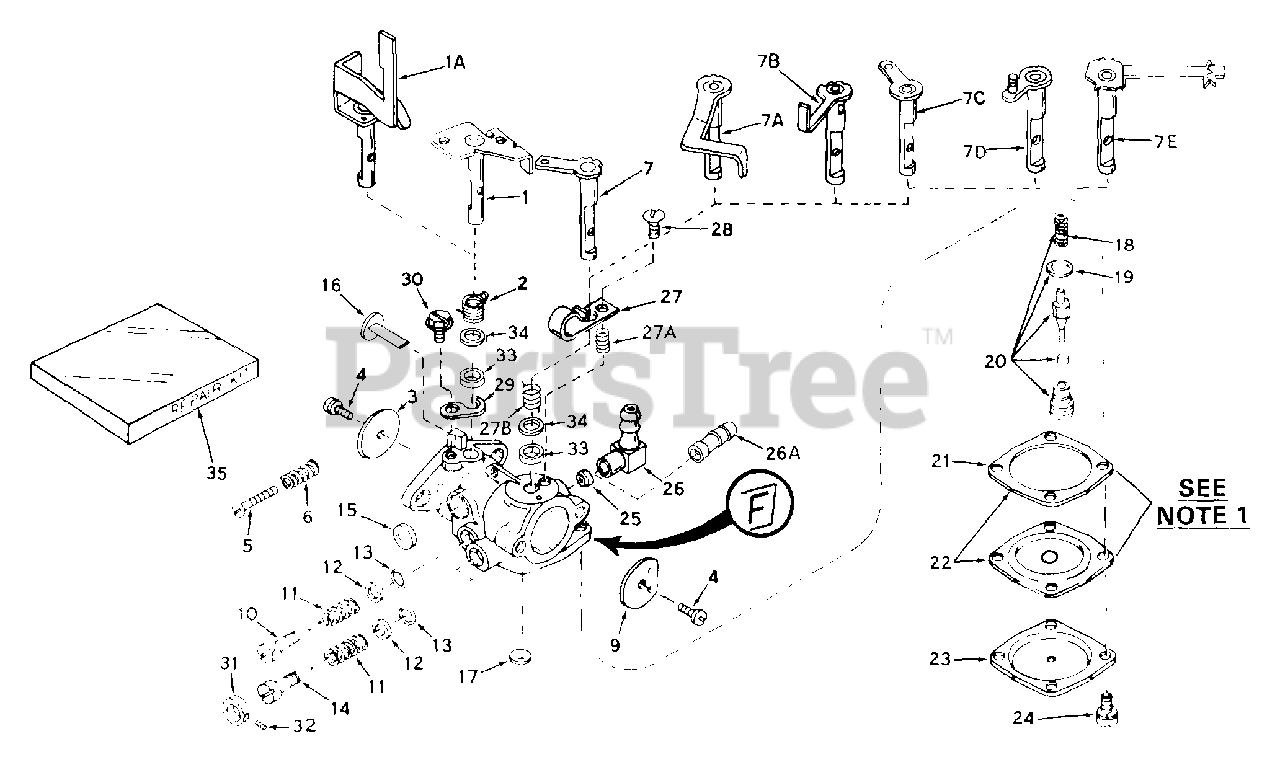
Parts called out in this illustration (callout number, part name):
1	"Shaft & Lever Assy., Throttle
2	Spring, Throttle return
3	Shutter, Throttle
4	Screw, Throttle & Choke shutter
5	Screw, Idle Regulating
6	Spring, Idle speed screw
7B	Shaft & Lever Assy., Choke
9	Shutter, Choke
10	Screw, Idle adj.
11	Spring, Adj. screw
12	Washer, Adj. screw
13	"O" Ring, Adj. screw
14	Screw, Main adj.
15	Plug, Welch
16	Element, Pump
17	Plug, Welch
18	Spring, Valve
19	Gasket, Valve seat
20	Inlet Needle, Seat, Spring & Gasket A ssy.,
21	Gasket, Diaphragm
22	Diaphragm Assy.
23	Cover, Diaphragm
25	Valve, Check
26	Fitting, Fuel inlet
27	Spring, Detent
29	Retainer, Throttle shaft
35	Repair Kit
